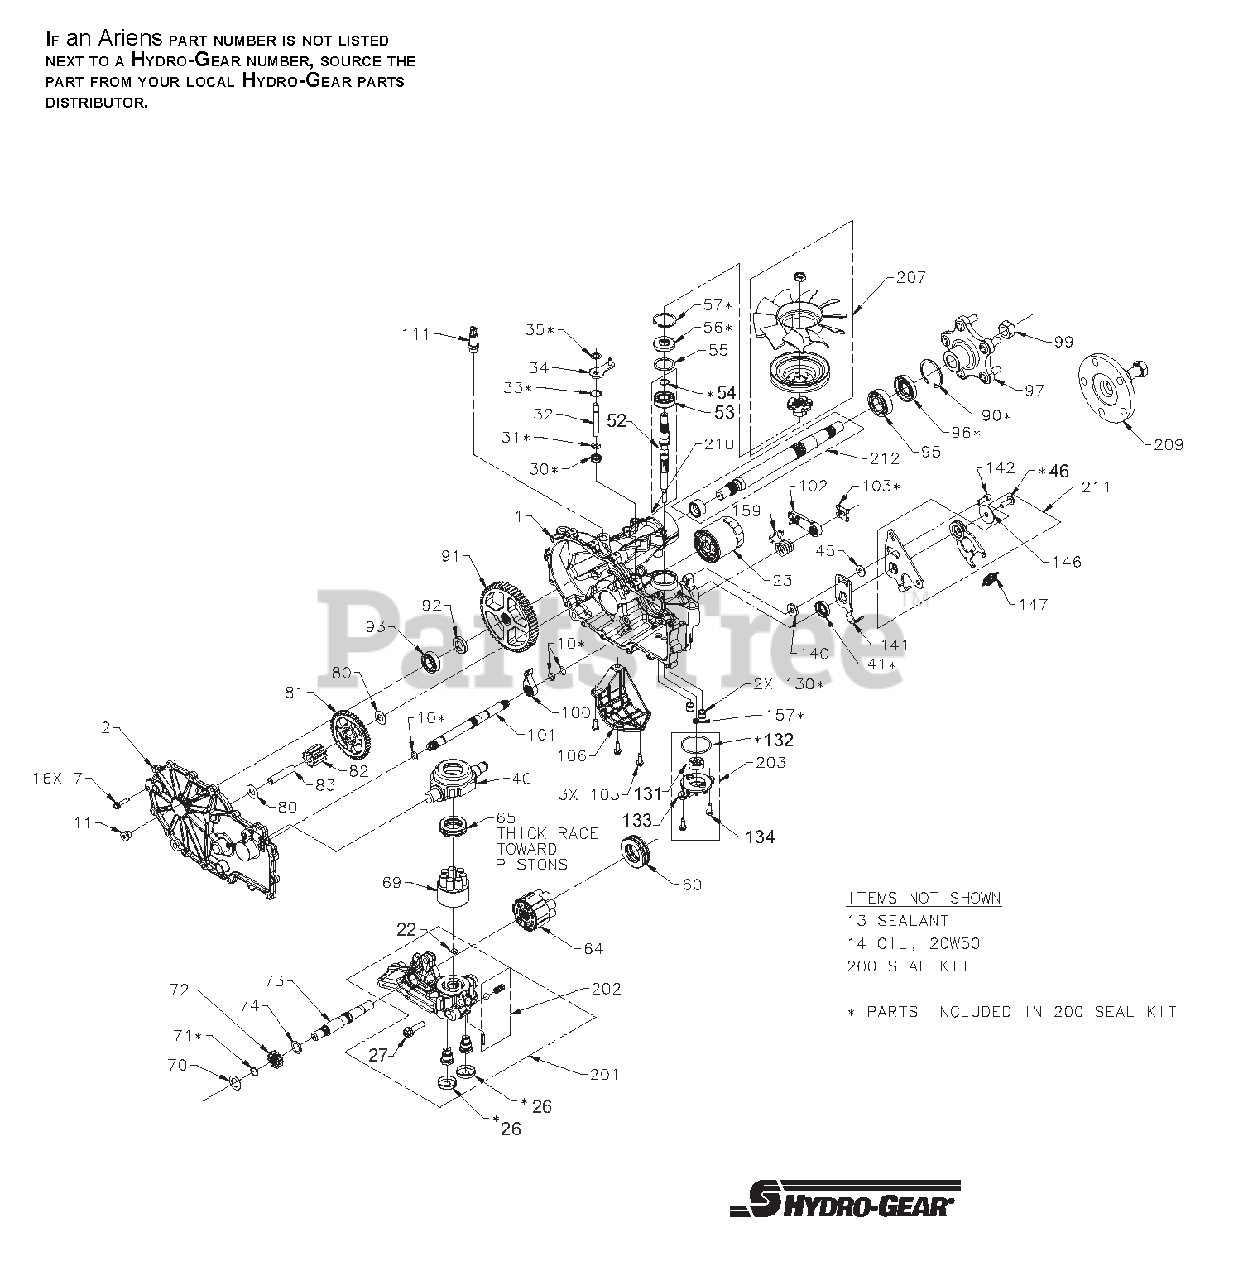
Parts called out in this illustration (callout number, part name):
1	Kit, Main Housing LH
7	HFHCS 1/4-20 X 1.25"
11	PLUG, STEEL (WITH SEAL)
22	PLATE, BYPASS
23	Filter, Oil
30	SEAL, LIP .375X.75X.25
31	RING. RETAINING
32	Rod, Bypass
33	RING, RET .750
34	Arm, Bypass
35	RING, RTNG .
40	TRUNNION, SWASHPLATE
46	TWHCS 5/16-24 X 1.00
52	Shaft, Input
53	BRG, BALL 17X40X12
54	Ring, Ret Wire .561 ID
55	WASHER 1.23X1.56X.04
56	SEAL, LIP 17X40X7
57	RING, RET 1.56 INT
60	Bearing, Thrust
65	BEARING. THRUST 30 X 52 X 13
70	WASHER .63X1.0X.05
71	RING, RET 62 EXT
72	Gear, 13T, Steel
73	Shaft, Motor
74	WASHER .71 X 1.16 X .04
80	WASHER .5X1.0X.032
83	JACK SHAFT (PIN)
90	RING, RETAINING
95	BEARING, BALL 25.4 X 52 X 15
96	SEAL, LIP
99	NUT, HEX, LOCK 3/4-16
103	Clip, Retaining
105	HFHCS 1/4-20X.75
106	Guard, Filter, LH
111	Fitting, Str 9/16-18 SAE .5 Barb
130	Tube, Connecting
131	GEROTOR
133	Cover, Charge Pump
134	HFHCS 1/4-20X.75
142	SHCS 5/16-24X1 PATCH
147	Spring, Extension Rtn - 34 lbs
200	Kit, Seal ( * - parts included in this kit)
NS	SEALANT TUBE 10.1OZ.
NS	20W50 Oil
